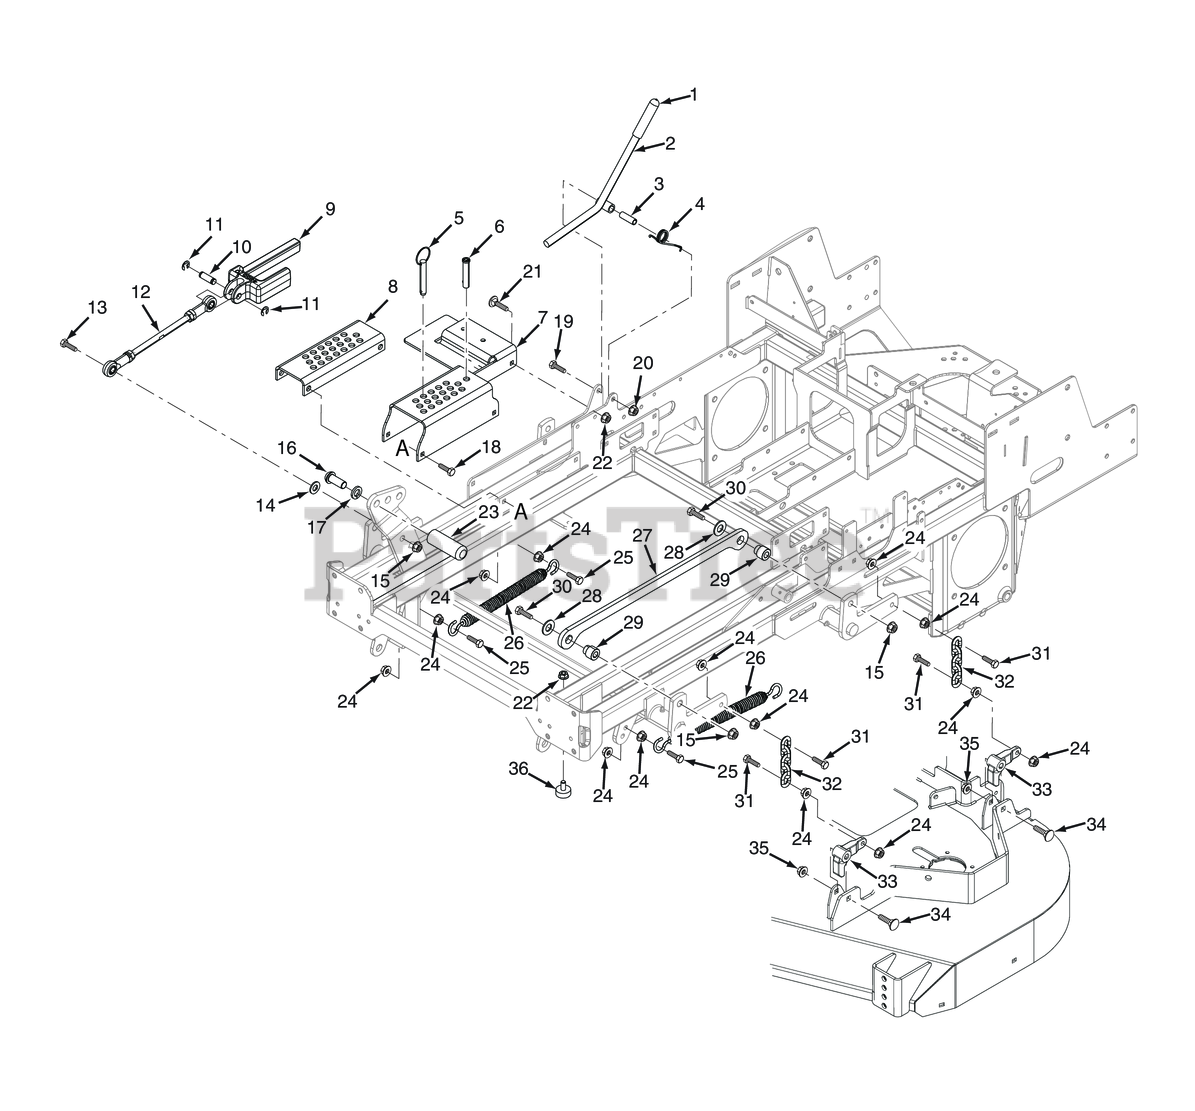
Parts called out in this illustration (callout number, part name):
1	Mounting Bracket, Fuel Tank
2	Deck Latch Assembly w/Grip
3	Bushing, .502 O.D.
4	Spring, Torsion - Lever Return
5	Lanyard, Deck Height Pin Assembly
6	Pin, Locking
7	Adjustment Bracket, Upper Cut Height
8	Adjustment Bracket, Lower Cut Height
9	Slide, Height Adjustment Assembly (INCL. 10,11,12)
10	Pin, Deck Lift
11	Retaining Ring, 1/2" Ext. "E"
12	Linkage, Deck Lift
13	Hex Head Bolt, 1/2-13 x 2"
14	Flatwasher, 1/2 - .531 x 1.062 x .095
15	HEX LOCKNUT, ELASTIC STOP, 1/2-13
16	Capscrew, 5/8-11 x 1-1/2"
17	Lockwasher, 5/8" Spring
18	Bolt, Hex Wshr Head 5/16-18 x 1-1/4"
19	Capscrew, Hex Head 3/8-16 x 2.75"
20	HEX NUT, ELASTIC STOP LOCK, 3/8-16
21	Bolt, 5/16-18 x .75 RHSN Carriage
22	Nut, Serrated Flange 5/16-18 (Right Front Engine Mounting, Briggs and Kohler Only)
23	Foot Pedal, Height Adjustment
24	NUT, 3/8-16 SERRATED FLANGE HEX HEAD
25	Bolt, Hex Head 3/8-16 x 1-1/2" Grade 8 Black
26	Spring, Helper (61" & 72" Cutter Decks Only)
27	Link, Deck Lift
28	Flat Washer, 1/2 (.562 x 1.375 x .109)
29	Pivot, Deck Link
30	Bolt, Hex Head 1/2-13 x 2-1/4"
31	Bolt, Hex Head, 3/8-16 x 1-1/2"
32	Chain, Deck Lift
33	Lever, Deck Level
34	Bolt, Carriage 7/16-14 x 2-1/4"
35	HEX LOCKNUT, ELASTIC STOP, 7/16-14
36	Bumper, Rubber 5/16-18 x 5/8"
